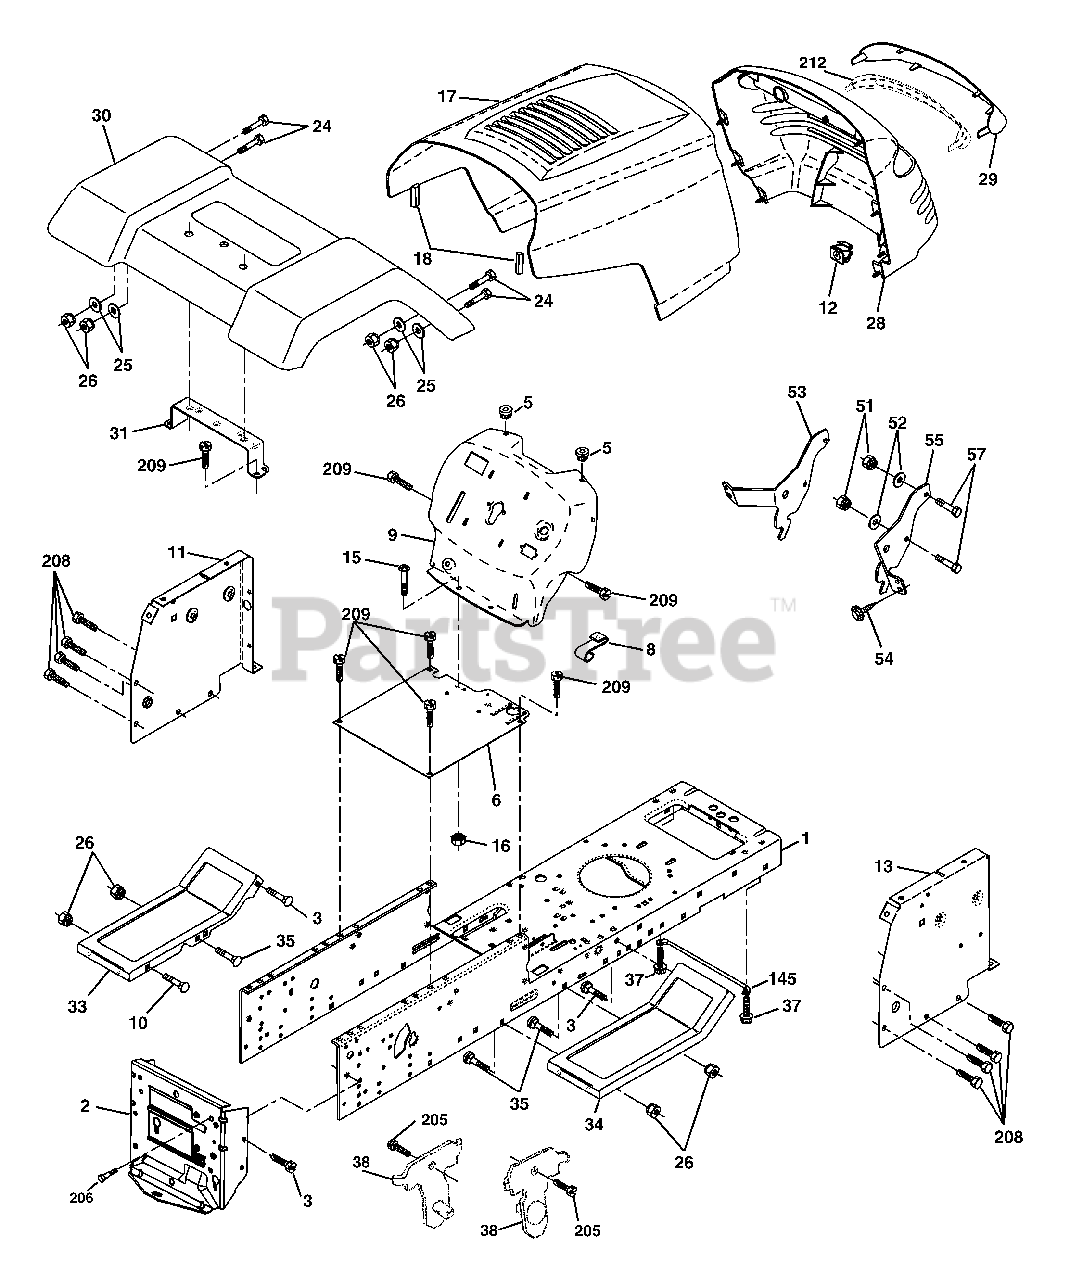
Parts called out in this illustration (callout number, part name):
1	Chassis
2	Drawbar, Stretch
3	Screw 3/8-16 x 3/4
5	Bumper, Hood/Dash
6	Saddle Silkscreen
8	Clip Retainer Slide-On
9	Dash
10	Bolt, Carriage 3/8-16 x 1
11	Panel Dash LH
12	Clip Tinnerman Grille P.L
13	Panel Slkscr Dash RH
15	Screw Mach TRHD 5/16-18uncx3/4
16	Nut Keps 5/16-18 Unc
17	Hood
18	Bumper Hood
24	Bolt Fin Hex 3/8-16unc X 1 Gr. 5
25	Washer 13/32 X 13/16 X 12 Ga
26	Nut Lock Hex w/Ins 3/8-16 Unc
28	Grille/Lens Asm.
29	Lens Grille Private Label
30	Fender
31	Bracket Fender Repl 109873x
33	Footrest Pnt LH
34	Footrest Pnt RH
35	Bolt Rdhd Sht Sqnk 3/8-16 X3/4
37	Screw Thdrol 5/16-18 x 1/2 TYT
38	Bracket Asm. Pivot Mower
51	Nut Lock W/Insert 1/4-20unc
52	Washer 9/32 x 7/8x16 Ga.
53	Bracket Grille Lh
54	Screw Hex 8-18 x 7/8
55	Bracket Grille Rh
57	Bolt Fin Hex 1/4-20 unc x .75
145	Rod Pivot Chassis/Hood
205	Screw Thdrol 3/8-16 x 1/2
206	Bolt Shoulder 5/16-18
208	Screw Thdrol 3/8-16 x 1/2
209	Screw Hex Wsh Thdrol 3/8-16
212	Insert Lens Reflect
